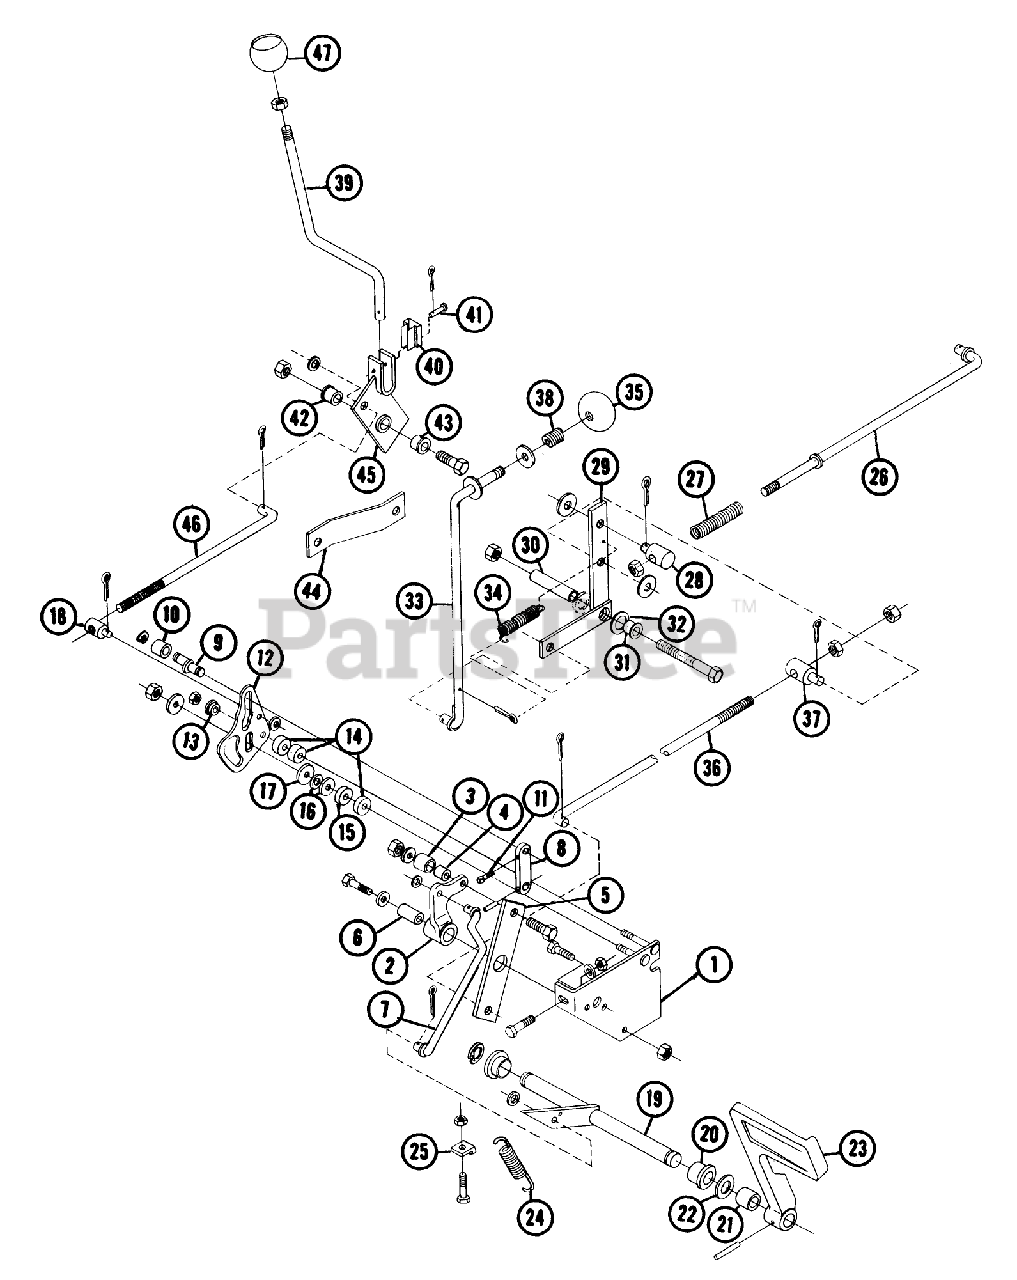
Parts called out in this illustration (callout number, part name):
1	Assy-Plate
2	Lever-Neutral Return
3	BEARING-CAM RETURN
4	SPACER
6	Spacer
7	ROD ASSY
8	Arm-Speed Control
9	ECCENTRIC-CAM FOLLOW
10	Spacer
11	SET SCREW
12	Cam-Speed Control
13	CAM-SPACER
14	Spacer
15	SPACER
16	WASHER-SPRING DISC
17	FRICTION WASHER
19	Assy-Shaft
20	BEARING
21	Spacer
22	WASHER
23	Brake Pedal
24	SPRING-EXTENSION
25	CLIP - SPRING
26	Assy-Rod
27	Spring
28	TRUNNION-LIFT
29	Assy-Arm Brake
30	Spacer
31	FLANGED BUSHING
32	Washer
33	Assy-Brake Rod
34	SPRING
35	SHIFT KNOB
36	Rod
37	TRUNNION-LIFT
38	SPRING-COMPRESSION
39	HANDLE
40	Spring
41	Clevis Pin
42	CAM-SPACER
43	FLANGED BUSHING
44	Brace
45	ASSY-PIVOT
